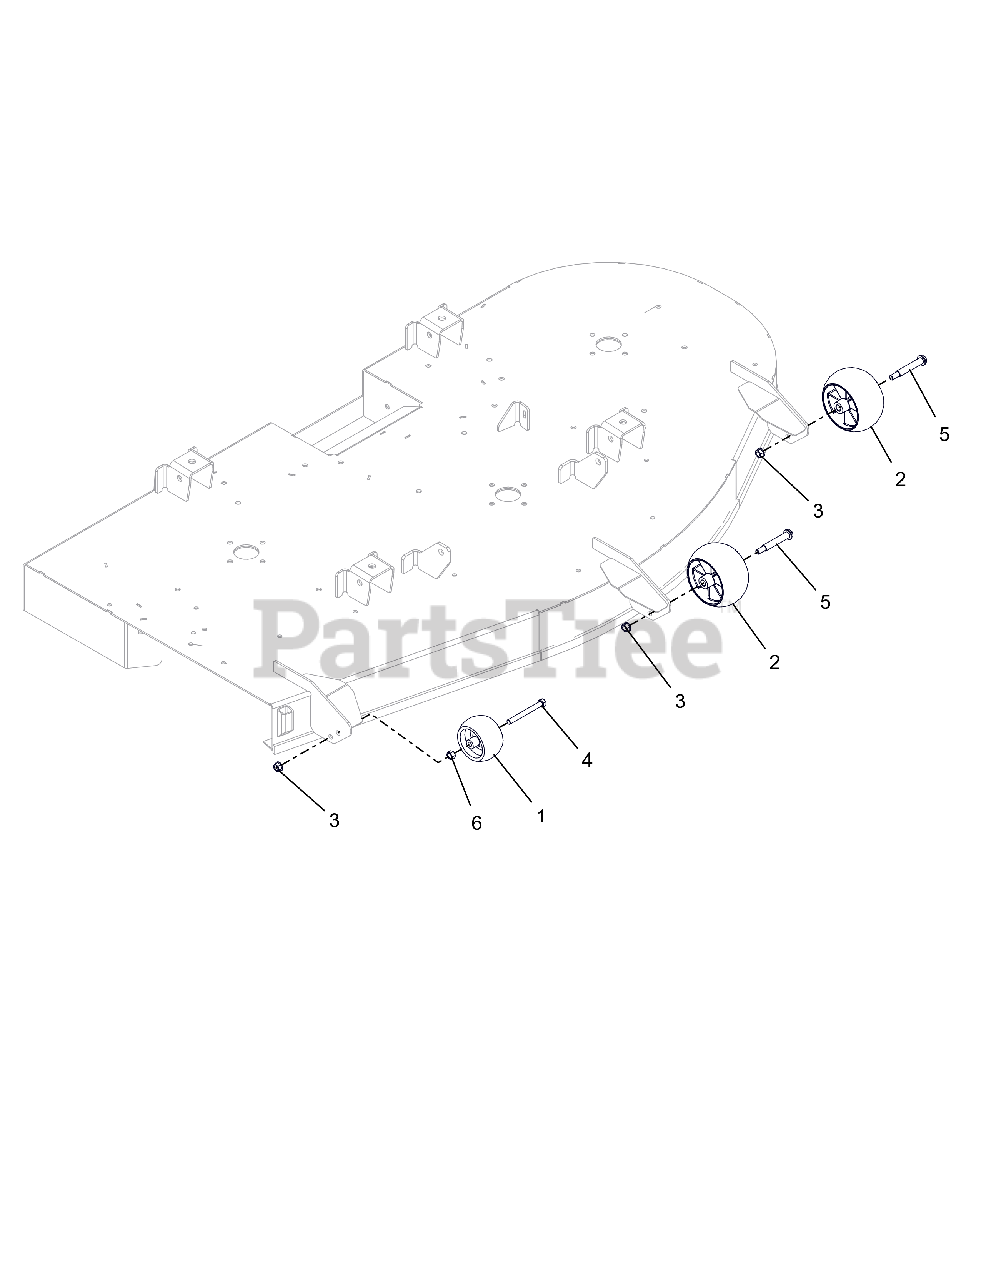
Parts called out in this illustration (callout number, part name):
2	ANTI-SCALP WHEEL - 5X OS
3	NUT-LK-TOP-FLG .38-16 ZC120
4	BLT, HEX .38-16X3.50 G5 ZCC
5	BLT-SHLDR .38-16X2.50 HWH G5
6	@NUT-HEX .38-16 YWZC
